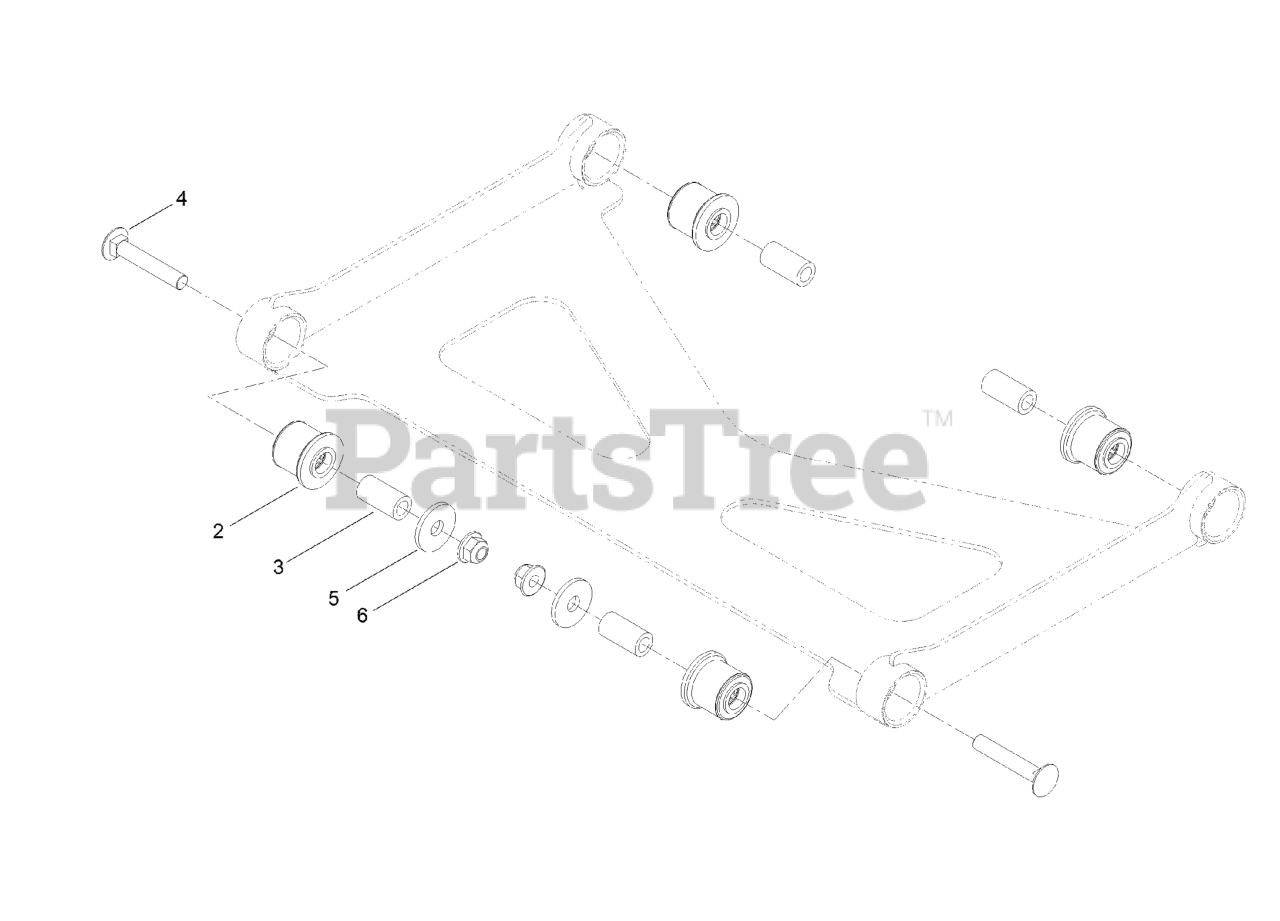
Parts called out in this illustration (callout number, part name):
2	BUSHING-RUBBER, SUSPENSION
4	Bolt-Carriage 3/8-16 X 2 1/4
5	WASHER
6	NUT-HF, NI
